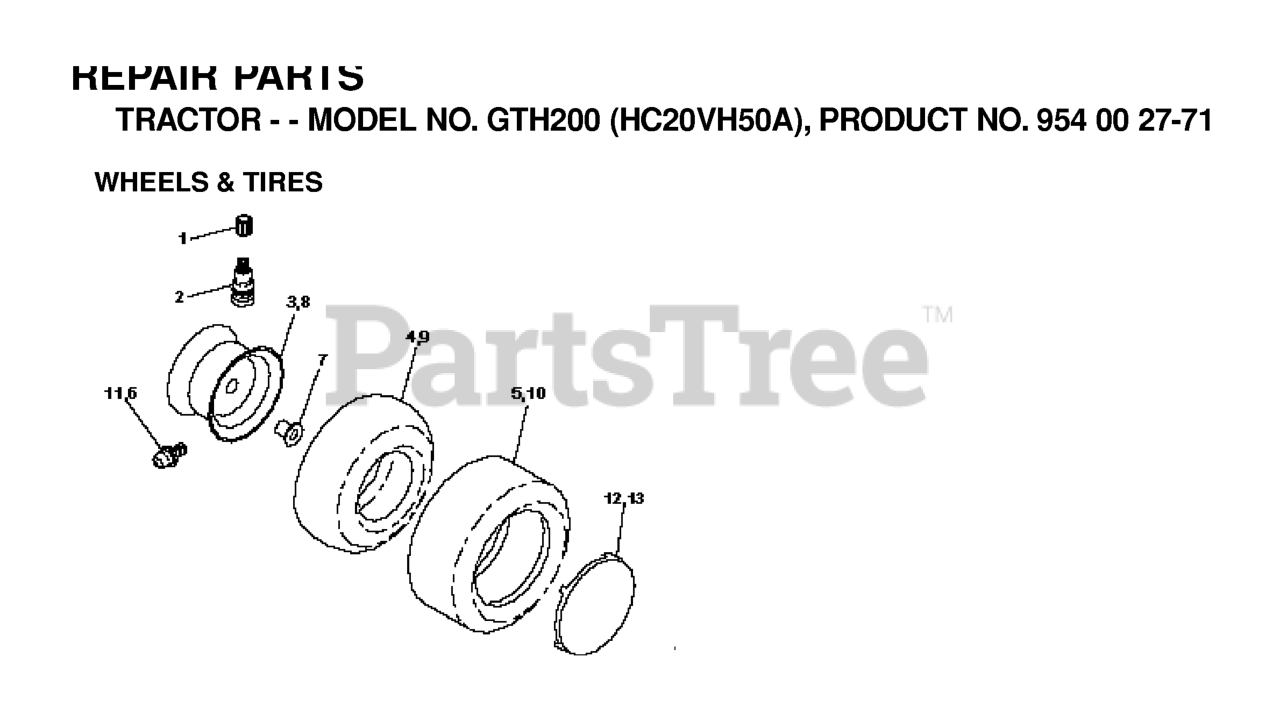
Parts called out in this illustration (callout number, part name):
2	VALVE STEM LT
3	RIM ASSY-FRONT
4	TUBE.16X6.5/7.5-8
5	TIRE HEAVY DUTY
6	FITTING LT
7	BEARING T
8	RIM.ASM.12X7.REAR.WHITE
9	TUBE.23X9.5-12
10	TIRE HEAVY DUTY
11	ZERK FITTING M
12	CAP,HUB REAR
13	COVER,WHEEL
